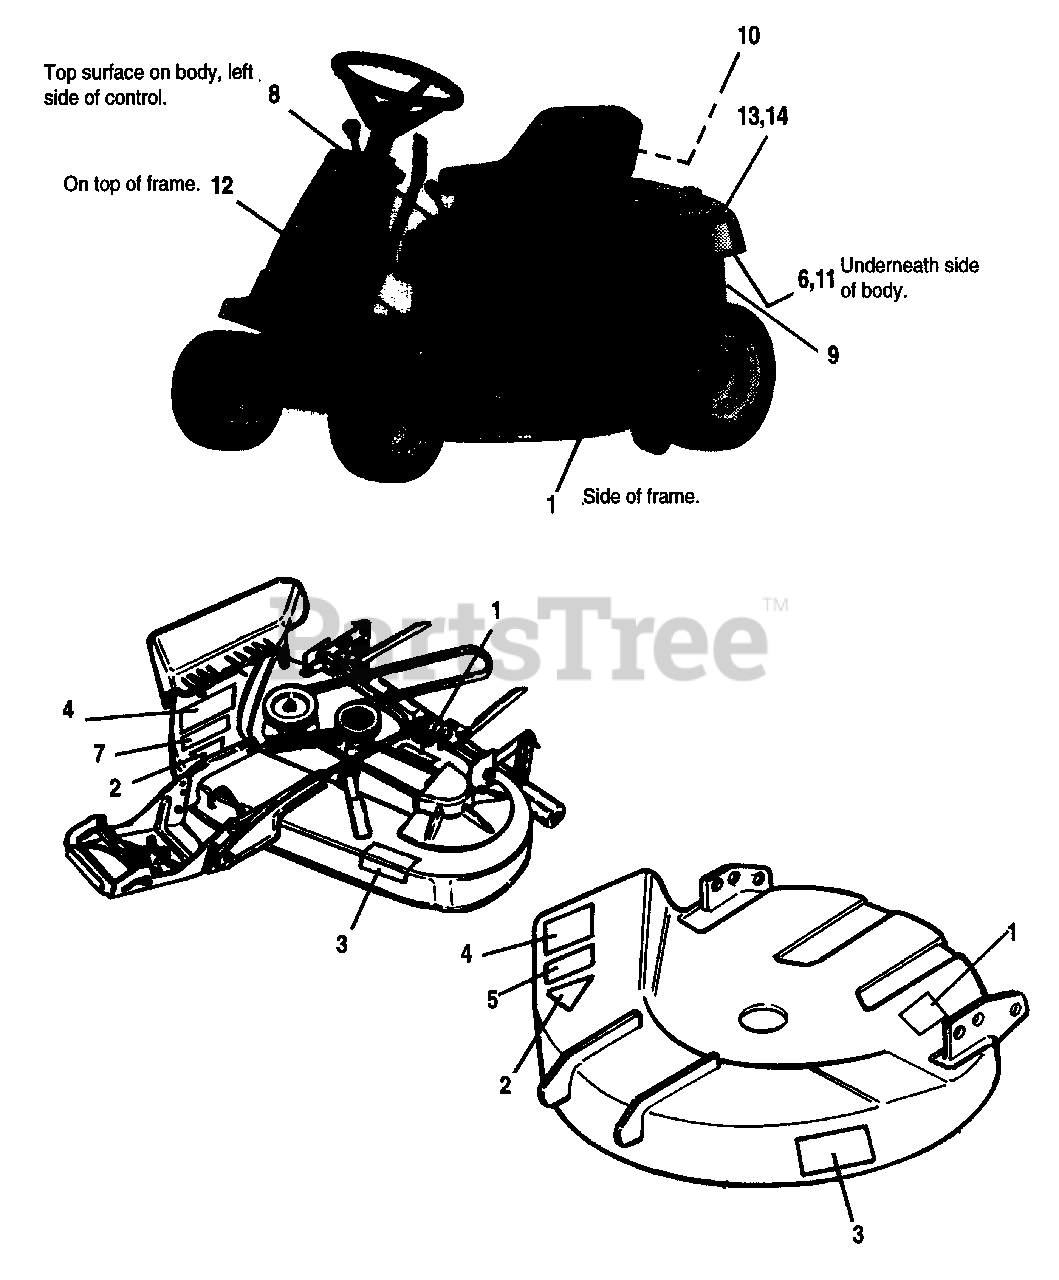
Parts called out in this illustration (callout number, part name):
1	I.D. PLATE
2	DECAL, OPEI
3	DECAL, Danger (Hand Under Deck)
4	DECAL, Danger (Chute In Place)
5	DECAL, Cutting Width-30"
6	DECAL, Belt & Blade Replacement
7	DECAL, Cutting Width-34"
8	DECAL, Throttle/Choke
9	DECAL, Transmission Release Valve (Hydro models only)
10	DECAL, USA (Seat back)
11	DECAL, Touch-up Paint
12	DECAL, Operating Instructions
13	DECAL, Seat Deck, LH (2409G)
13	DECAL, Seat Deck, LH (2412H)
14	DECAL, Seat Deck, RH (2409G)
14	DECAL, Seat Deck, RH (2412H)
